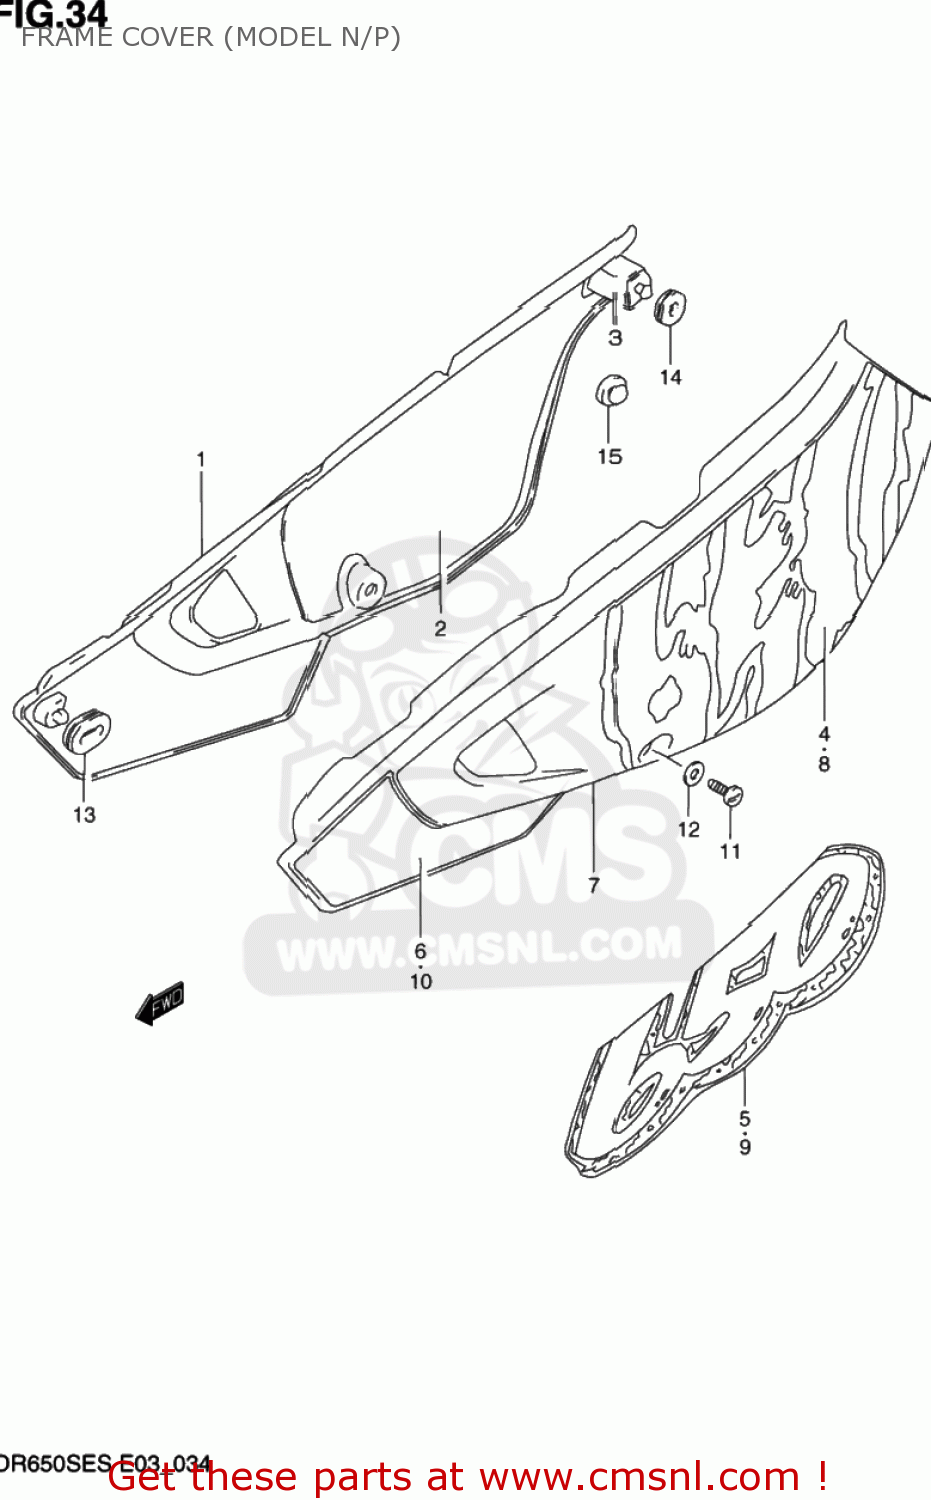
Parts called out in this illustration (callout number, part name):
1	COVER,FRAME,RIGHT
2	SHIELD,FRAME COVER,R
3	SHIELD,FRAME COVER,R NO.2
4	TAPE,FRAME COVER,RIGHT
5	EMBLEM,FRAME COVER,RIGHT
6	TAPE,FRAME COVER NO.2
7	COVER,FRAME,LEFT
8	TAPE,FRAME COVER
9	EMBLEM,FRAME COVER,LEFT
10	TAPE,FRAME COVER NO.2
11	SCREW
12	WASHER
13	CUSHION
14	CUSHION
15	CUSHION
